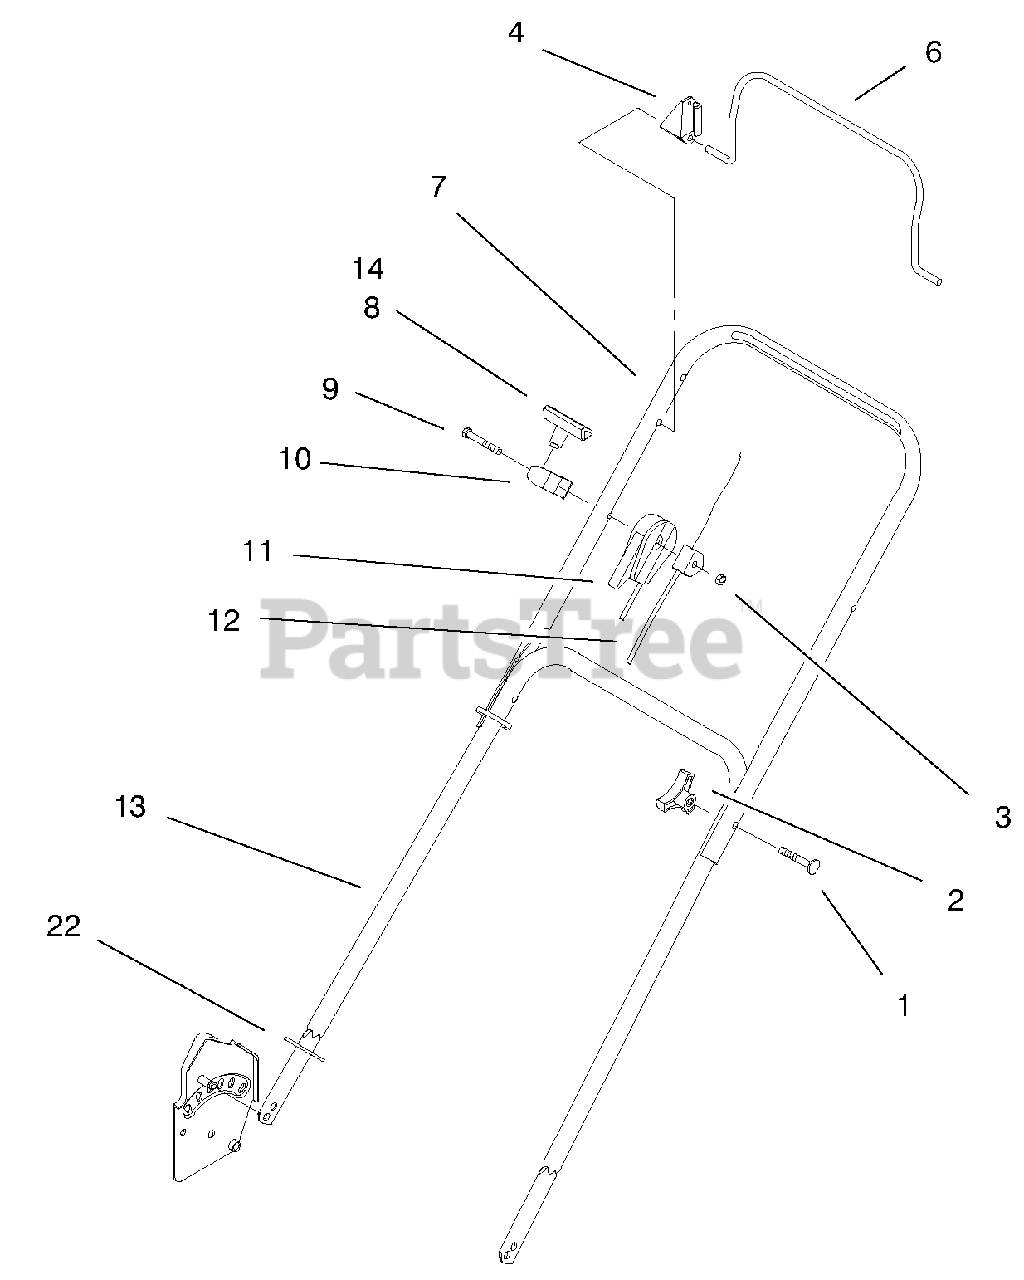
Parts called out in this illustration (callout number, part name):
1	Screw-Handle
2	Knob
3	Nut-Lock
4	Stop-Pivot
6	Bail-Flywheel Brake
7	Handle-Upper
8	Handle-Starter
9	Screw-Hex Hd. Cap
10	Guide-Rope
11	Cable-Throttle
12	Cable-Brake
13	Handle-Lower
14	Staple-Handle
22	Guard-Handle
